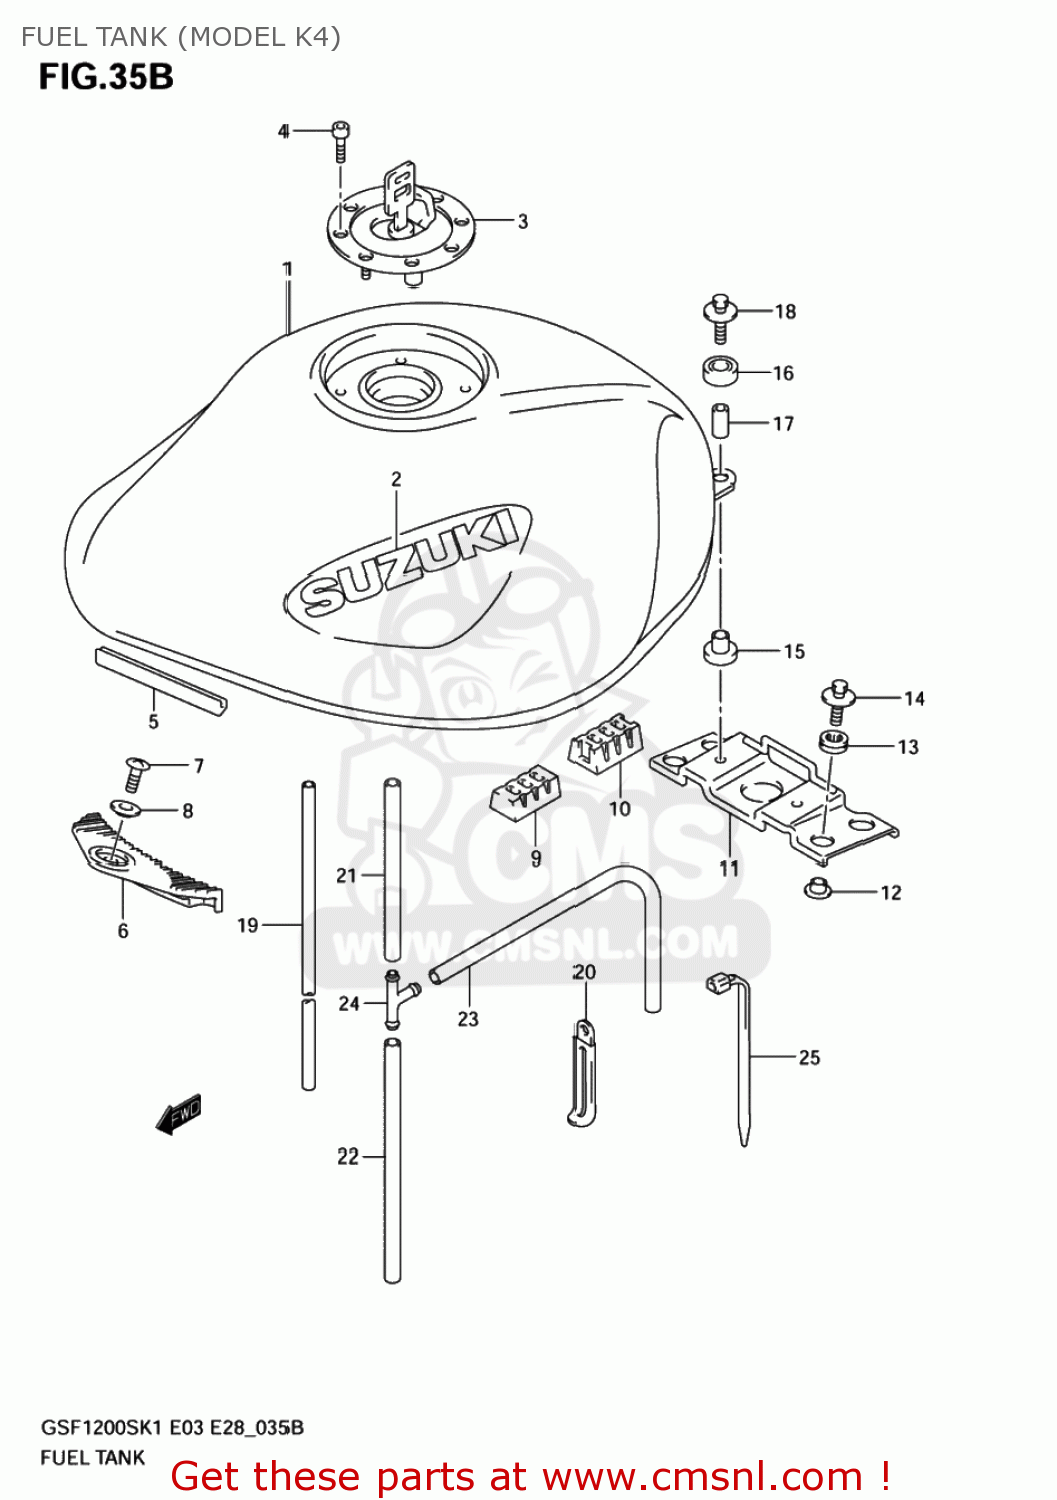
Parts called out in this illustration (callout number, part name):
1	TANK ASSY,FUEL(GRAY)
2	EMBLEM(BLACK)
3	CAP SET,FUEL TANK
4	BOLT(5X20)
5	MOLDING
6	CUSHION,FUEL TANK FR
7	SCREW
8	WASHER
9	CUSHION,SUPPORT(50X25X32)
10	CUSHION,TANK SIDE
11	BRACKET,FUEL TANK RR
12	WASHER
13	CUSHION
14	BOLT(6X25)
15	CUSHION
16	CUSHION,FUEL TANK RR
17	SPACER(6.5X9X18)
18	BOLT(6X30)
19	HOSE(7X11X2000)
20	CLAMP(L:97)
21	HOSE(5X8.2X600)
22	HOSE(5X8.2X600)
23	HOSE(5X8.2X600)
24	JOINT,3 WAY
25	CLAMP(L:125)
